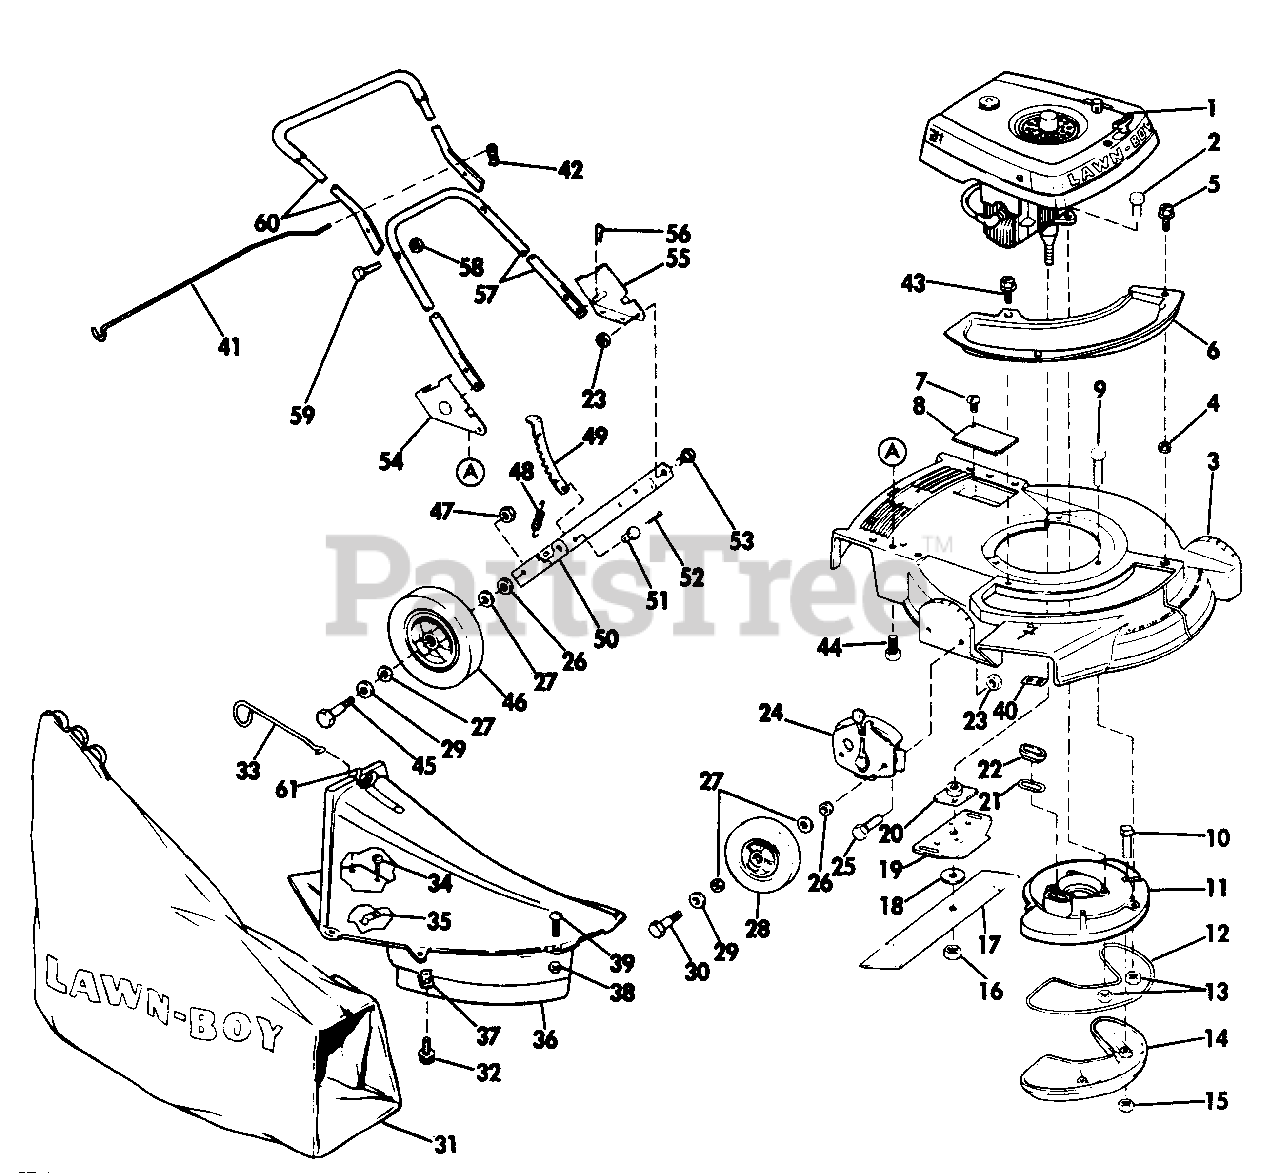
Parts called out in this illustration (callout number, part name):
1	Engine-Model D-408
2	Screw-Crankcase to Muffler Plate
3	Housing Assembly 21"
4	Grommet
5	Hex Head Screw
6	Cover-Chute Opening (Plastic)
7	Screw
8	Cover-Pocket
9	Screw-Muffler Plate to Housing
10	Screw-Muffler to Muffler Plate
11	Muffler Plate
12	Gasket-Muffler
13	Nut-Nylok
14	Muffler
15	Nut-Muffler
16	Nut-Blade
17	Blade-21"
18	Washer
19	Stiffener-Blade
20	Collar & Plate Assembly
21	Gasket-Exhaust
22	Sleeve-Muffler Gasket
23	Nut-Nylok
24	Height Adjustment Assy.
25	Screw-Height Adjustment Bracket
26	Washer
27	Felt Washer
28	Wheel & Tire Assembly 6"
29	Washer-Wheel Bolt Head
30	Bolt-Shoulder, Wheel
31	Bag & Frame Assembly
32	Screw-Long
33	Wheel Guard
34	Screw
35	Speed Nut
36	Chute-Skirt Assembly
37	Speed Nut
38	Nut
39	Screw
40	Speed Nut
41	Rod & Clip Assembly
42	Clip-Rod
43	Screw
44	Screw-Handle Bracket
45	Bolt
46	Wheel & Tire Assembly 8"
47	Nut
48	Spring
49	Lever
50	Bracket
51	Pin
52	Cotter Pin
53	Bolt
54	Bracket-Handle, Right
55	Bracket-Handle, Left
56	Hairpin
57	Handle-Bottom
58	Nut-Handle
59	Screw-Handle
60	Handle & Grip Assembly Top
61	Clip Assy.-Chute (Plastic)
61	Clip Assy.-Chute (Metal)
